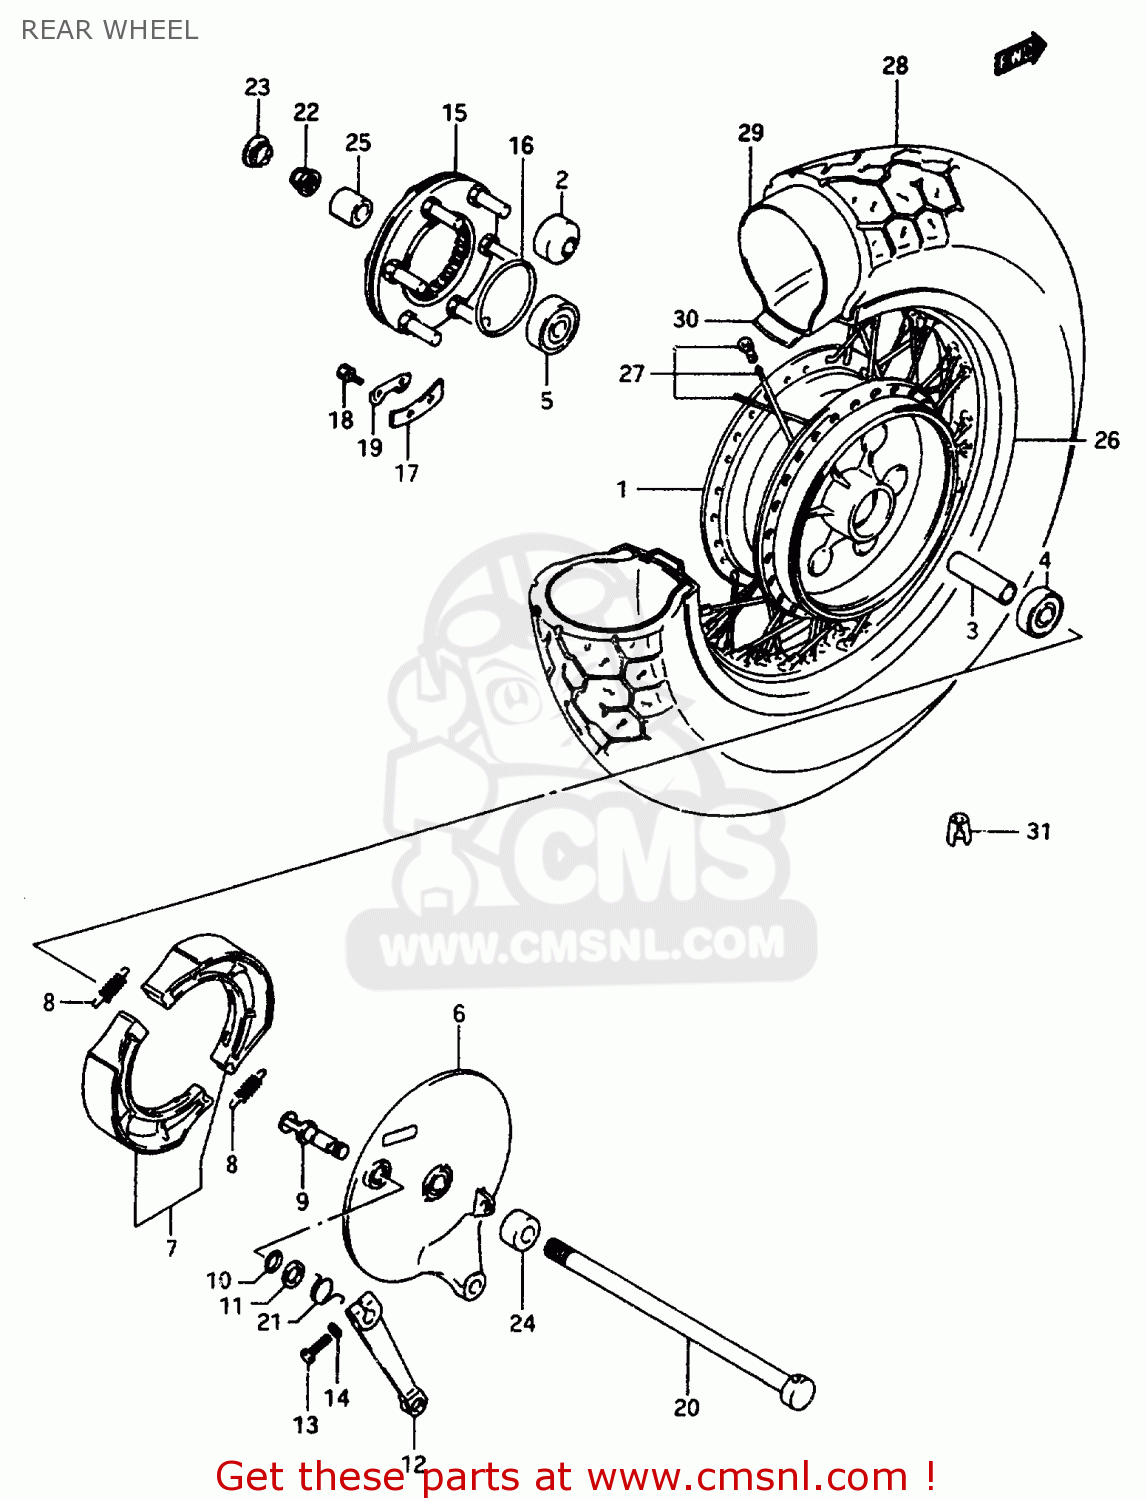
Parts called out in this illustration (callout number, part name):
1	HUB SET,RR
2	BUSH
3	SPACER(17.5X25X80)
4	BEARING
5	BEARING
6	PANEL,REAR BRAKE ANCHOR
7	SHOE SET,BRAKE (NAS)
8	SPRING, SHOE
9	CAM,RR BRAKE
10	O RING(D:2.4,ID:14.8)
11	WASHER (15X24X1.6)
12	LEVER,RR BRAKE CAM
13	BOLT
14	WASHER,LOCK
15	JOINT ASSY,RR HUB DRIVEN
16	O RING(D:2.1,ID:65)
17	WASHER,THRUST(T:1.6)
18	BOLT(6X16)
19	WASHER
20	AXLE,RR
21	SPRING
22	NUT
23	CAP,RR AXLE,R
24	SPACER,REAR AXLE,RIGHT
25	SPACER,RR AXLE,L
26	RIM,RR WHEEL MT(3.00X15 M/C)
27	SPOKE ASSY,RR WHEEL
28	TIRE,REAR 140/90-15M/C
29	TUBE ASSEMBLY,WHEEL,INNER
30	PROTECTOR,WHL INR TUBE
31	BALANCER,WHEEL
